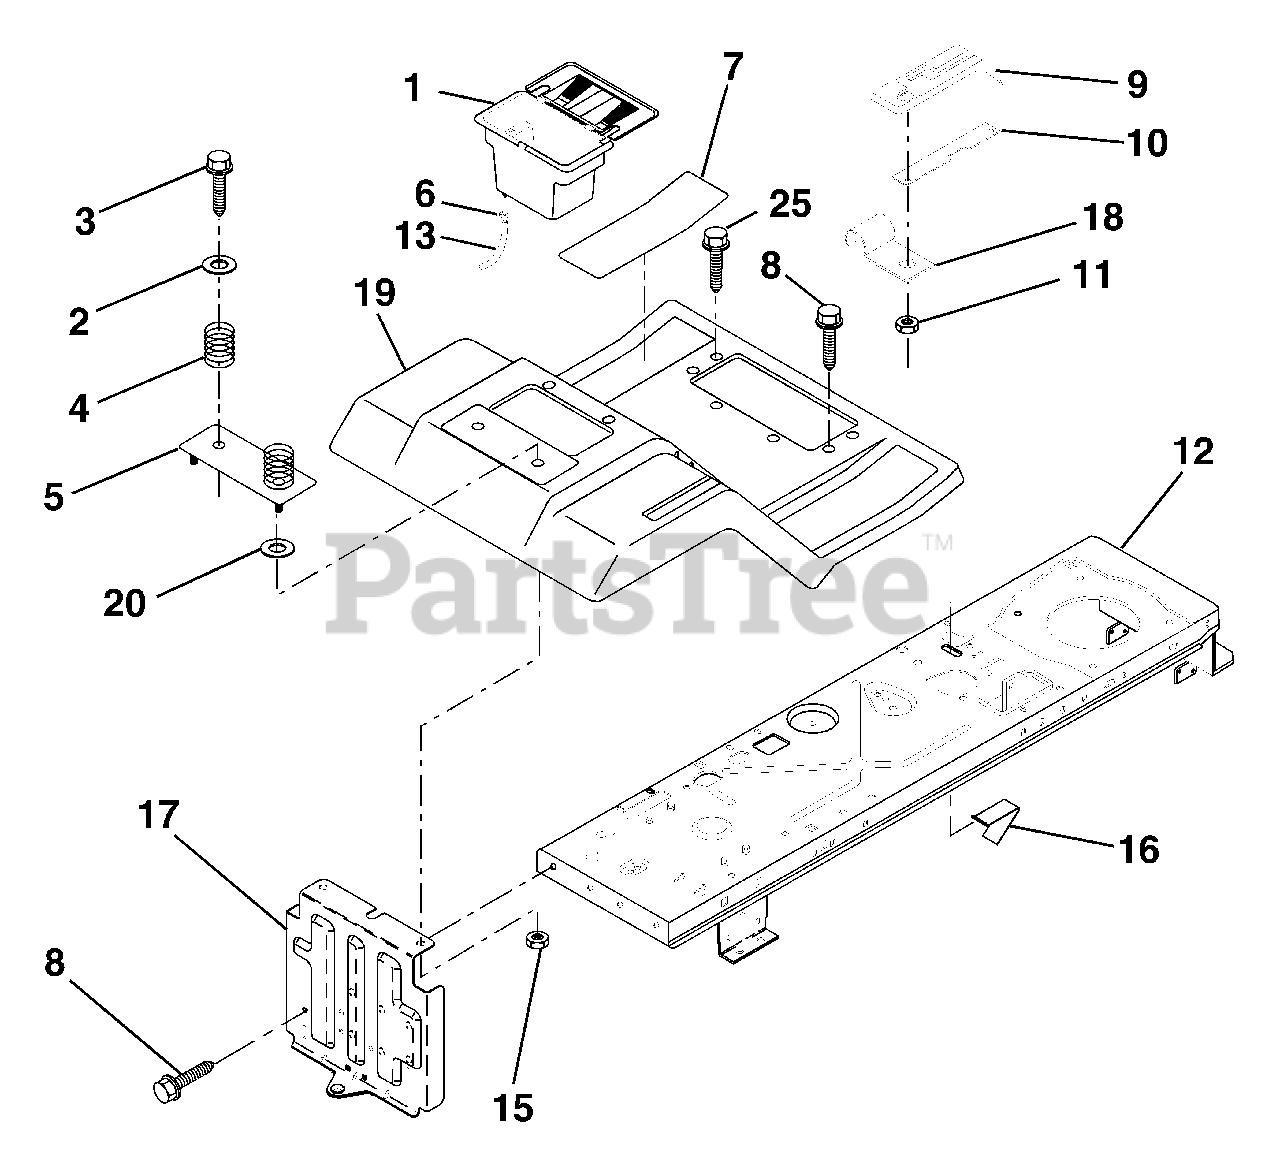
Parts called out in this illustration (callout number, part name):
1	Case, Battery
2	Washer 13/32 x 1-1/4 x 12 Ga.
3	Screw, Hex Wsh. Thrdrol 3/8-16 x 3/4
4	Spring, Compression, Seat
5	Plate, Asm. Battery
6	Clamp, Hose
7	Pad, Footrest
8	Screw, Thdrol 5/16-18 x 3/4
9	Console, Shift Control
10	Bar, Shift Lock
11	Nut, Self-Threading, Wsher Hd 3/16
12	Assembly, Frame
13	Tube, Battery Drain
15	Nut, Keps 1/4-20 UNC
16	Switch Actuator
18	Clip, Insulated
19	Fender/Footrest
20	Washer 9/32 x 7/8 x 13 Ga.
25	Screw Hex 5/16-18 Unc x1
